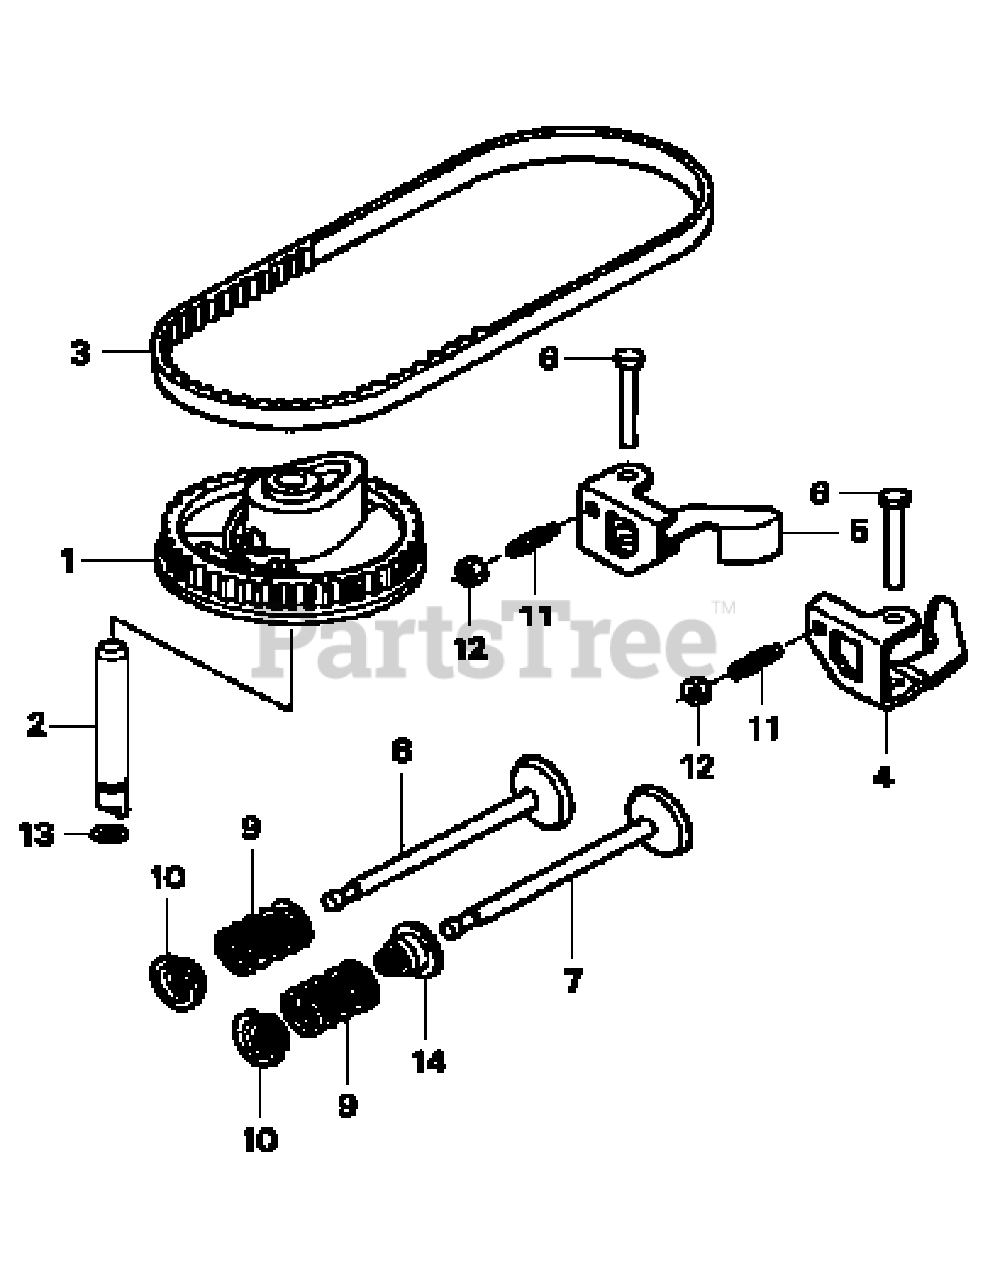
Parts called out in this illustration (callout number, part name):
1	Camshaft Pulley
2	Cam Pulley Shaft
3	Timing Belt
4	Valve Rocker Arm (Intake)
5	Valve Rocker Arm (Exhaust)
6	Rocker Arm Shaft
7	Intake Valve
8	Exhaust Valve
9	Valve Spring
10	Valve Spring Retainer
11	Tappet Adjustment Screw
12	Tappet Adjustment Nut
14	Valve Stem Seal
